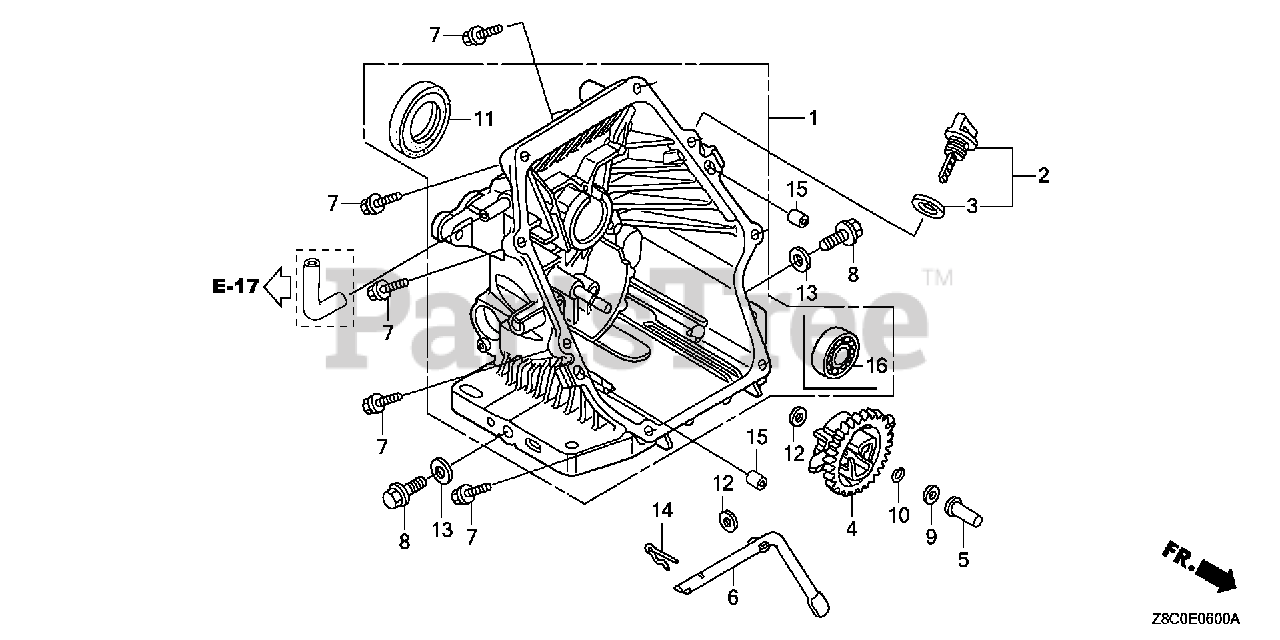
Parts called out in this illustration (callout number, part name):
1	COVER ASSY., CRANKCASE
2	CAP ASSY., OIL FILLER
3	GASKET, OIL FILLER CAP
4	GOVERNOR ASSY.
5	SLIDER, GOVERNOR
6	SHAFT, GOVERNOR ARM
7	BOLT, FLANGE (6X25) (CT200)
8	BOLT, DRAIN PLUG (12X15)
9	WASHER, THRUST (6MM)
10	CLIP, GOVERNOR HOLDER
11	OIL SEAL (28X41.25X6)
12	WASHER, PLAIN (6MM)
13	WASHER, DRAIN PLUG (12MM)
14	PIN, LOCK (8MM)
15	PIN, DOWEL (8X20)
